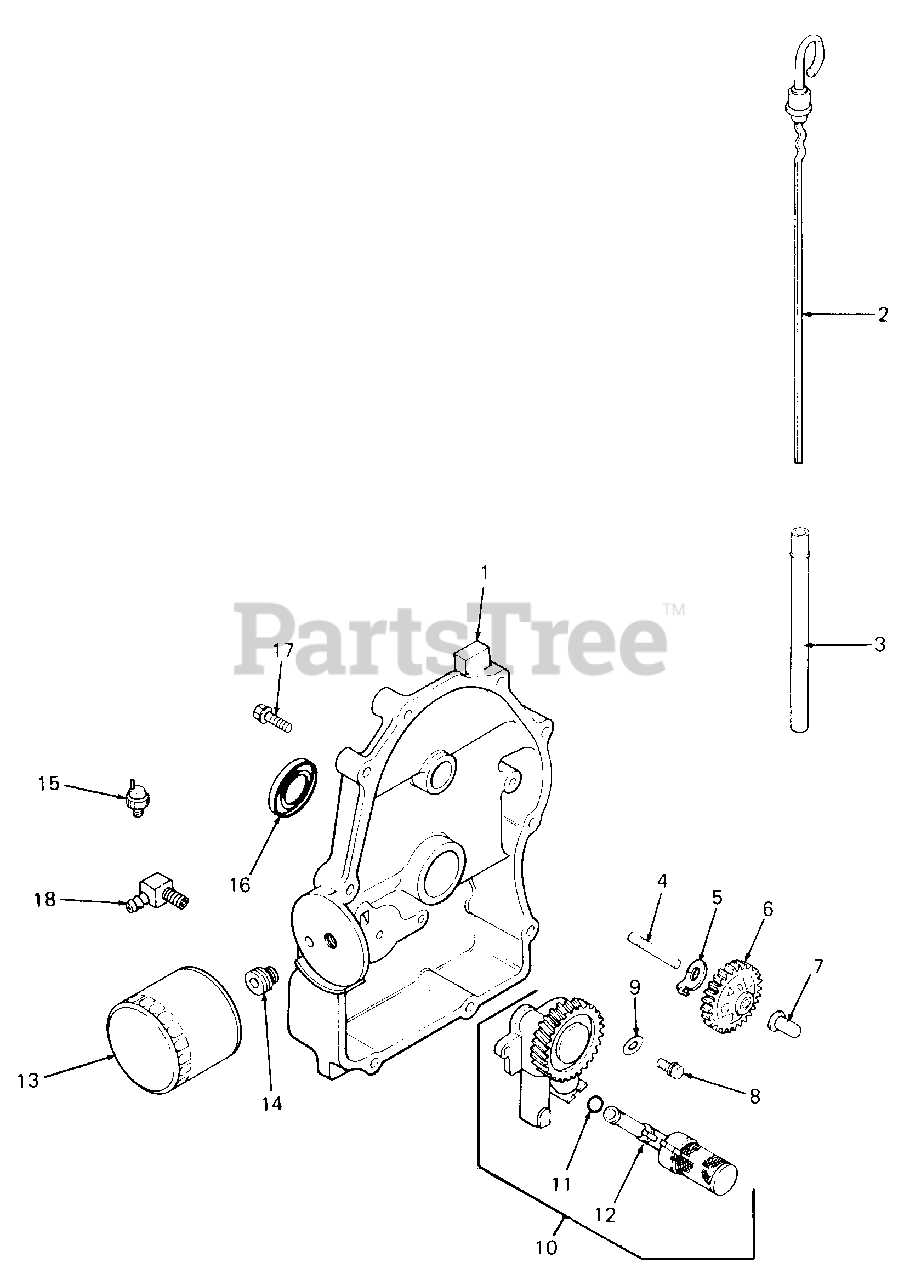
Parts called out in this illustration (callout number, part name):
1	Plate, Closure
2	Dipstick
3	Tube, Dipstick
4	Shaft, Governor Gear
5	Tab, Locking
6	Governor Gear Assembly
7	Pin, Governor Regulating
8	Screw
9	Washer
10	Oil Pump Assembly
11	O-Ring, Oil Pick-Up
12	Pick-Up, Oil
13	Filter, Oil
14	Adapter, Oil Filter
15	Switch, Oil Pressure
16	Seal, Oil (PTO end)
17	Screw, Closure Plate, M8 X 1.25 X 45
18	Connector, 90ø Hose
